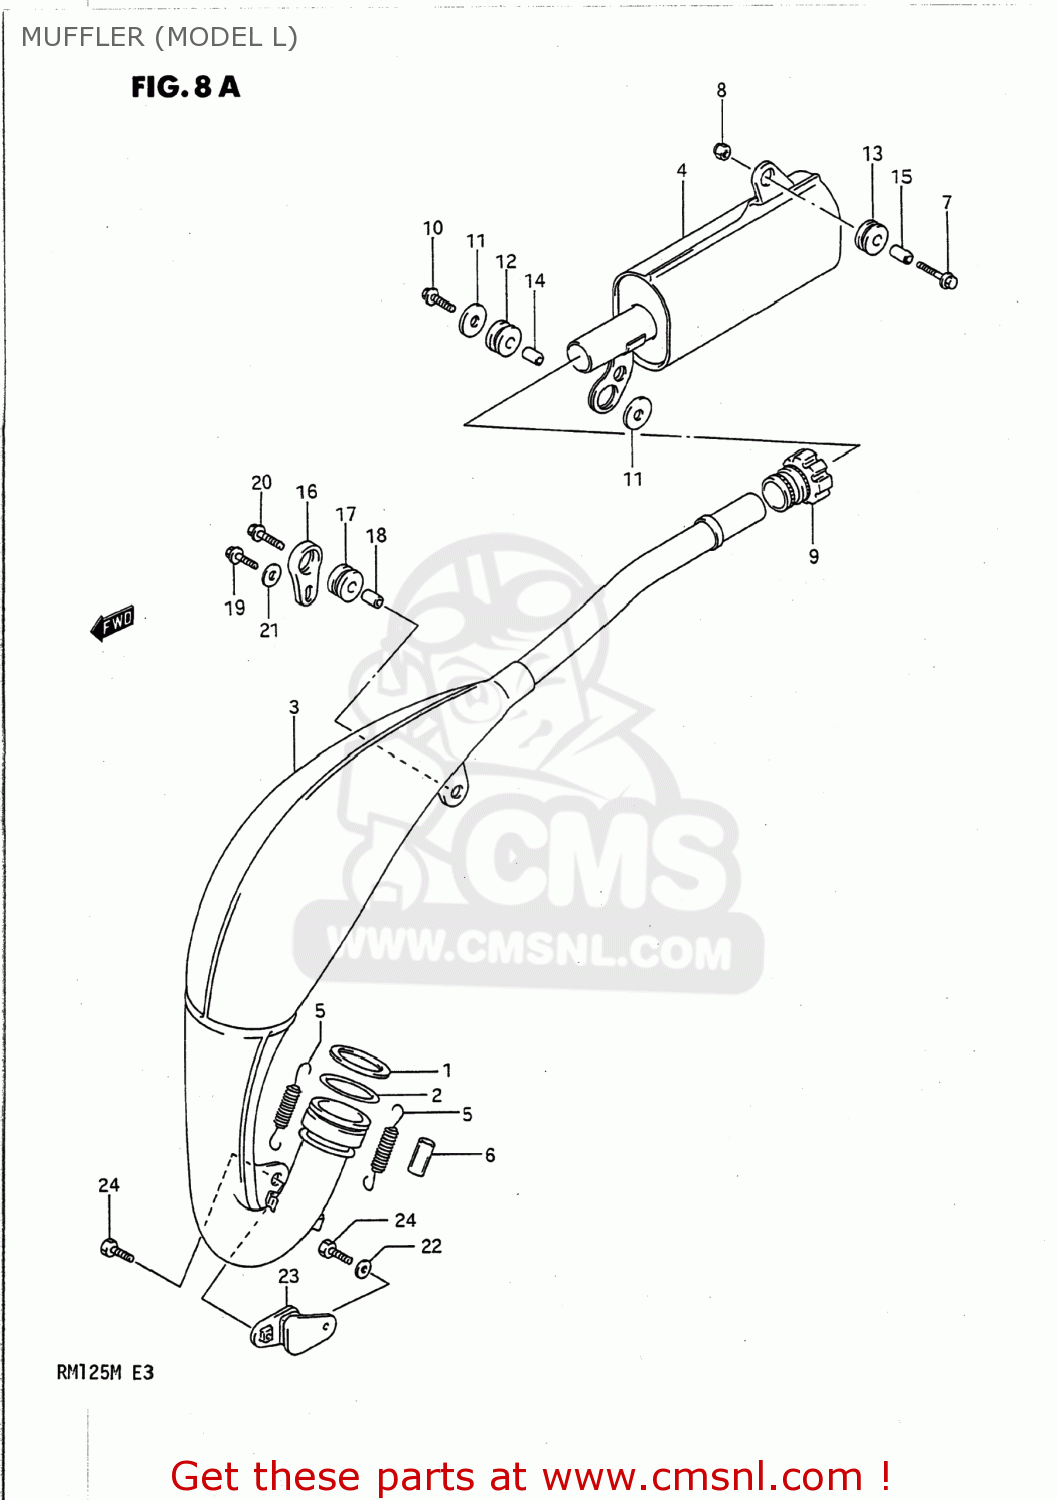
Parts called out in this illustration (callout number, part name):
1	WASHER,EXHAUST PIPE
2	O RING,EXHAUST PIPE
3	BODY,MUFFLER
4	BODY,MUFFLER
5	SPRING
6	HOSE
7	BOLT
8	NUT 6MM
9	CONNECTOR,2ND MUFFLER
10	BOLT
11	WASHER (6.5X24X1.2)
12	CUSHION
13	CUSHION
14	SPACER (6.8X10X9)
15	SPACER(6.5X11.5X13)
16	PLATE,MUFFLER MTG
17	CUSHION,MUFFLER
18	SPACER (6.4X9X13.5)
19	BOLT
20	BOLT
21	WASHER (6.5X20X1.2)
22	WASHER
23	DAMPER,MUFFLER SUPPORT
24	BOLT
